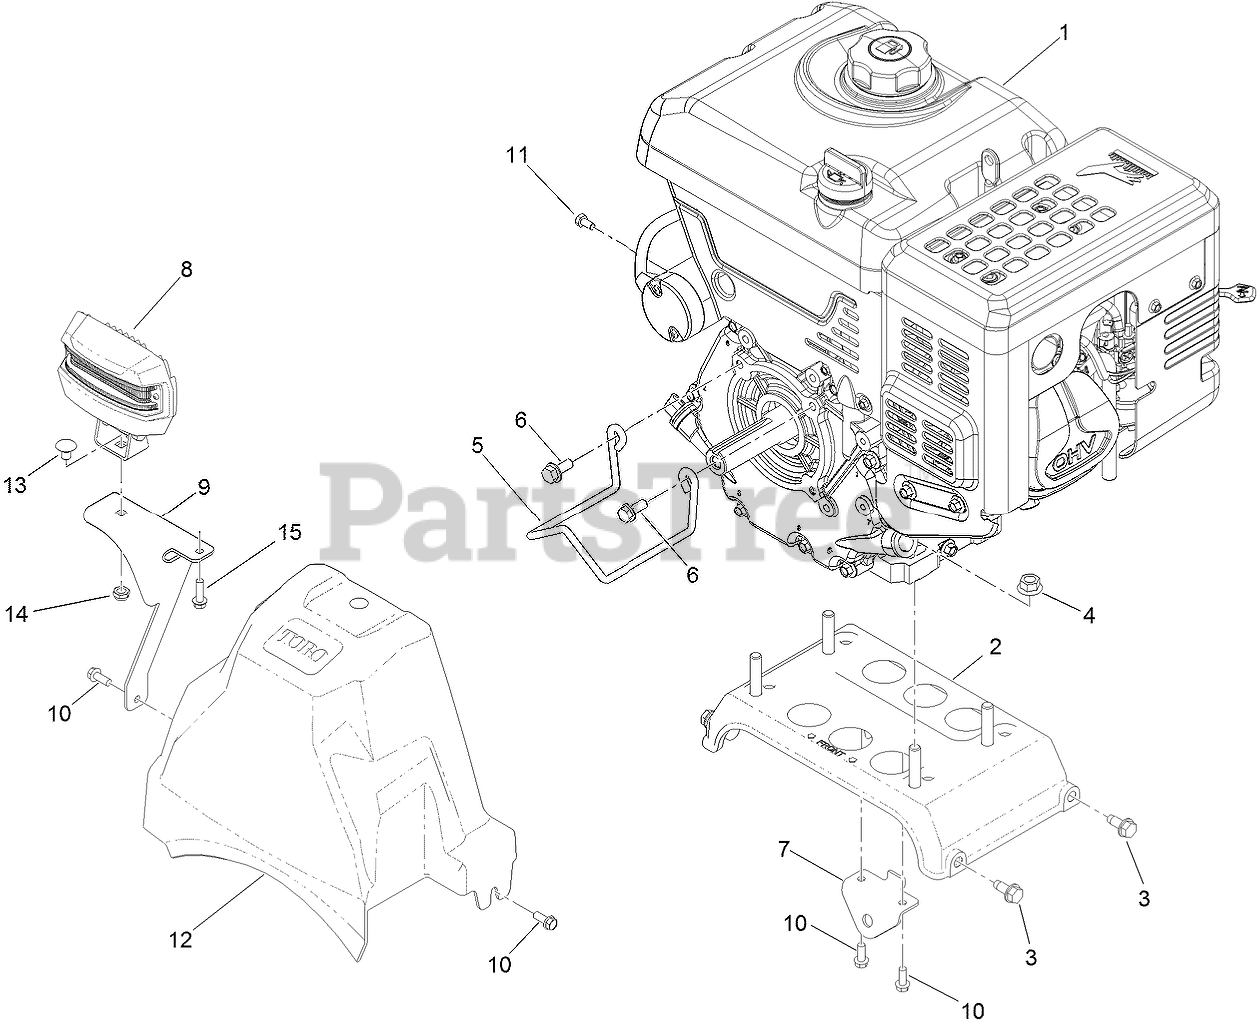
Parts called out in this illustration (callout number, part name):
1	ENGINE-180FDS-1
2	ENGINE PLATE ASM
3	SCREW-HWHTF
4	NUT-LOCK
5	GUIDE-BELT
6	SCREW-HH
7	BRACKET-CONTROL, TRACTION
8	LED LIGHT ASM
9	BRACKET-LIGHT
10	SCREW-HWH
11	SCREW-HH
12	COVER-BELT
13	BOLT-CARR
14	NUT-HEX
15	SCREW-PLASTITE, HWH
